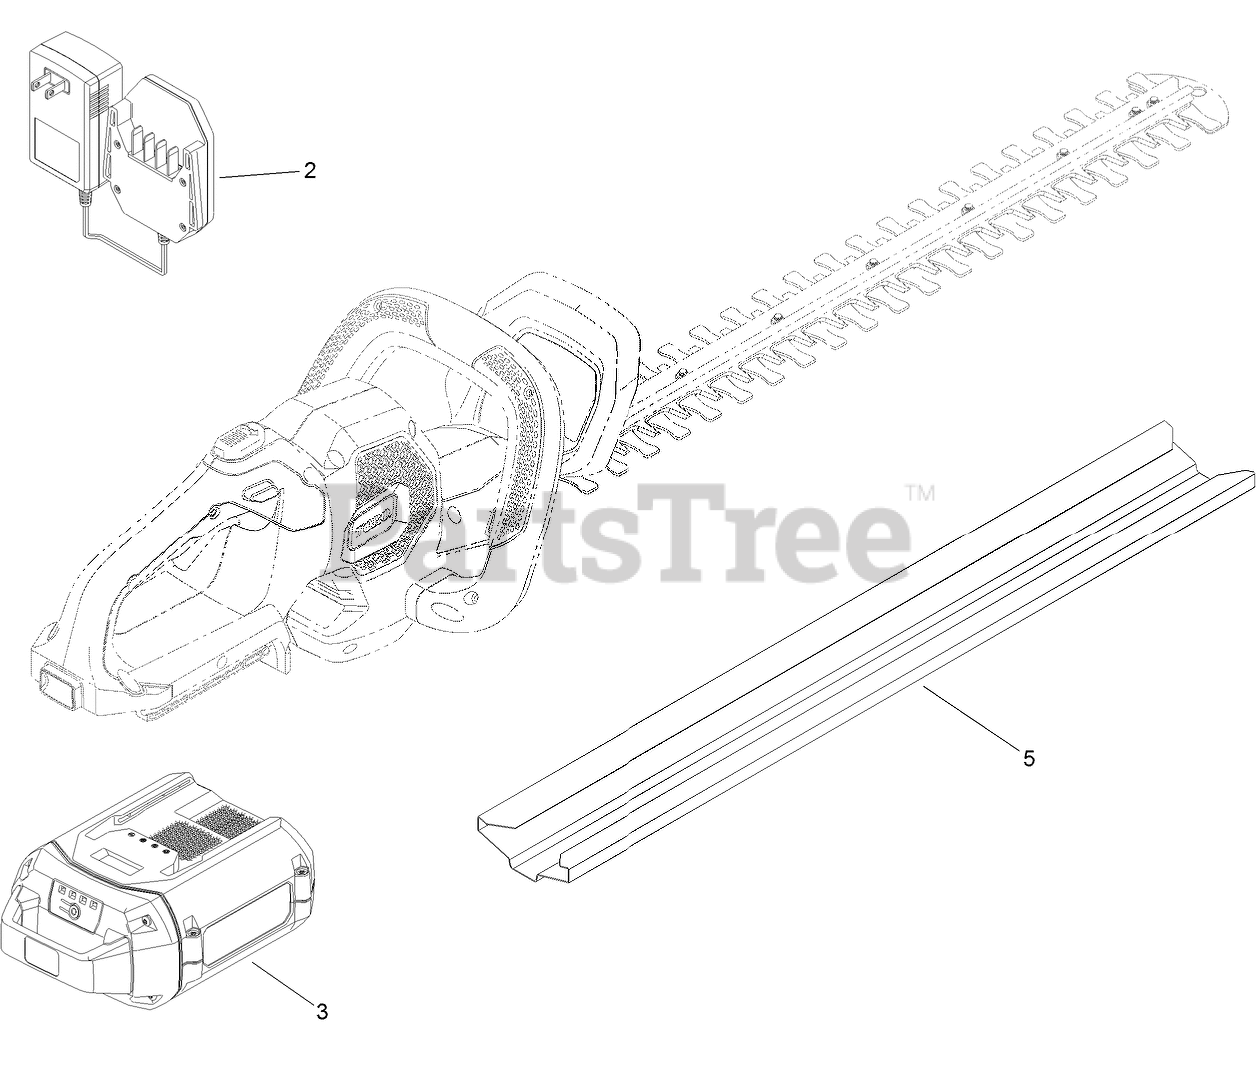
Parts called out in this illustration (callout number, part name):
2	CHARGER-BATTERY, 60V 1 AMP
3	BATTERY-60V 2.0AH
5	SLEEVE-BLADE
